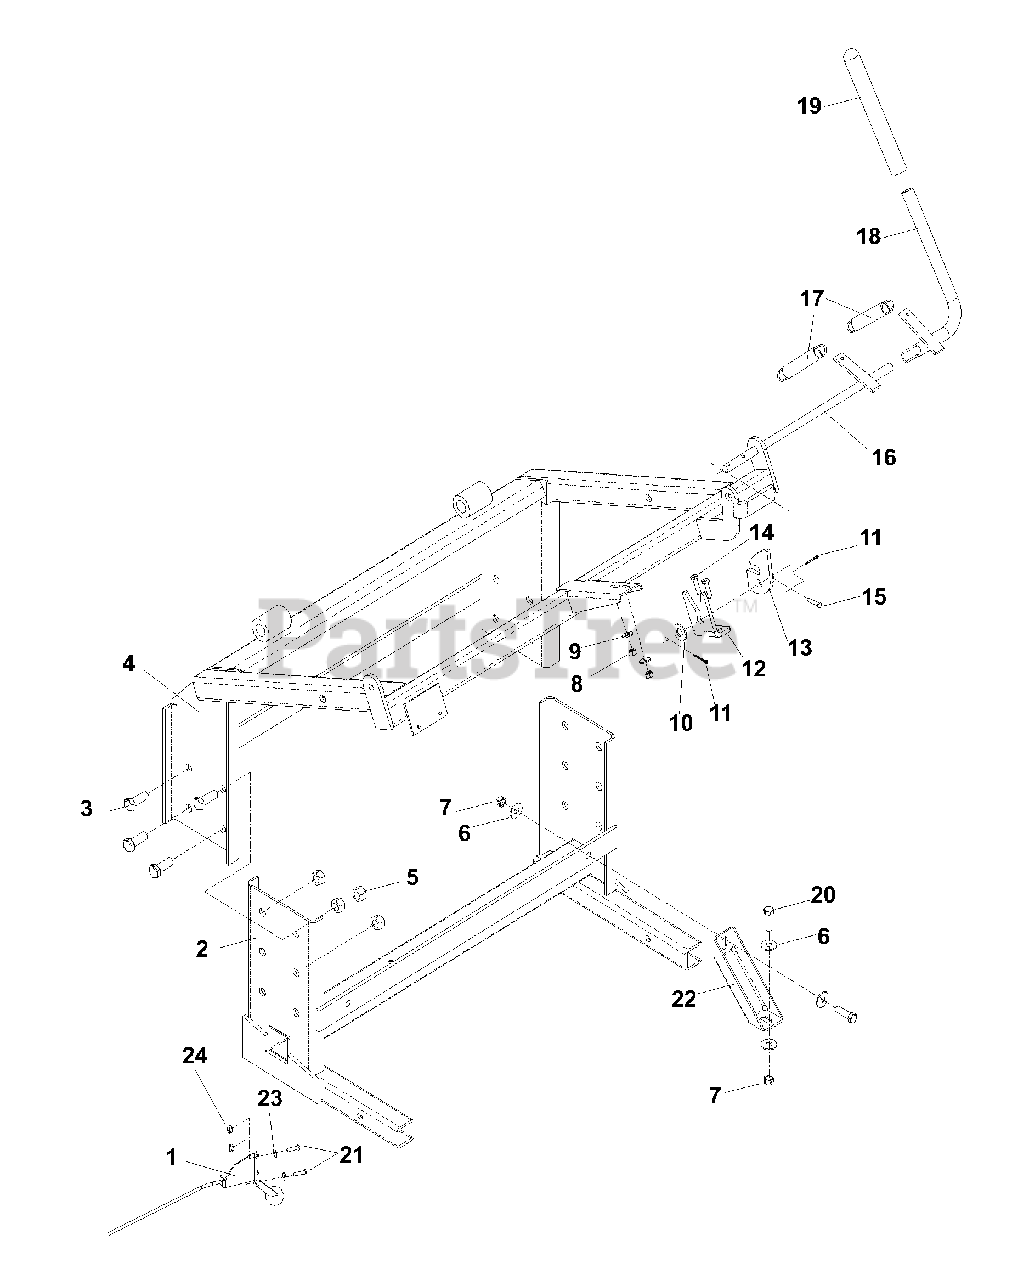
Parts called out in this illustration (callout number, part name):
1	THROTTLE CABLE
2	LOWER FRAME
3	BOLT, 1/2-13 X 1 1/4
4	UPPER FRAME
5	NUT, 1/2-13, NYLOC
6	WASHER 3/8 FLAT
7	NUT, 3/8-16, NYLOC
8	NUT, 1/4-20, NYLOC
9	WASHER, 1/4
10	WASHER, 1/2
11	COTTER PIN, 3/32 X 3/4
12	LATCH BASE
13	LATCH CATCH
14	BOLT, 1/4-20 X 1
15	CLEVIS PIN, 3/16 X 1
17	SPRING
18	RELEASE LEVER
19	GRIP
20	BOLT, 3/8-16 X 1 1/4
21	SCREW, #10-24 X 3/4, RD. HD., SLOTTED
22	HITCH BRACKET
23	WASHER #10 FLAT
24	NUT, #10-24, NYLOC
